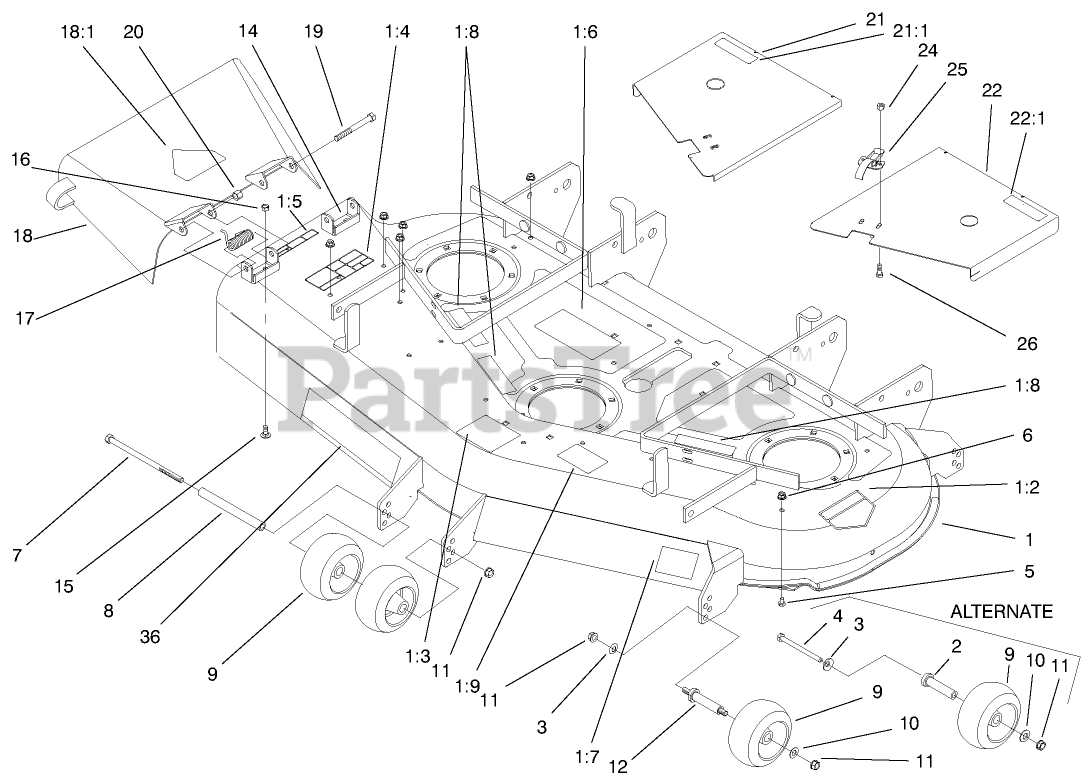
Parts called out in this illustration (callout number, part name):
1	Deck ASM
1:2	DECAL-DANGER
1:3	DECAL-WHEEL, GAGE
1:4	DECAL-DANGER, THROWN OBJECT
1:5	DECAL-DANGER
1:6	DECAL-BELT ROUTING
1:7	DECAL
1:8	DECAL-COVER, MISSING
1:9	DECAL-TORQUE, BLADE BOLT
2	SPACER-WHEEL
3	WASHER-BELLEVILLE
4	SCREW-HH
5	SCREW-HH
6	NUT-HF
7	SCREW-HH
8	SPACER-WHEEL
9	WHEEL-GAGE
10	Washer
11	NUT-HHF, WHIZ
12	SPACER
14	BRACKET-PIVOT
15	SCREW-CARR
16	NUT-LOCK, CONE
17	SPRING
18	DEFLECTOR ASM, 52" W/DECAL
18:1	DECAL-DANGER
19	SCREW-HH
20	NUT-HEX
21	COVER ASM-RH
21:1	DECAL-DANGER
22	LH COVER ASM
22:1	DECAL-DANGER
24	NUT-LOCK, FLANGE
25	CLAMP-SLOTTED
26	SCREW-HWH
36	DECAL
